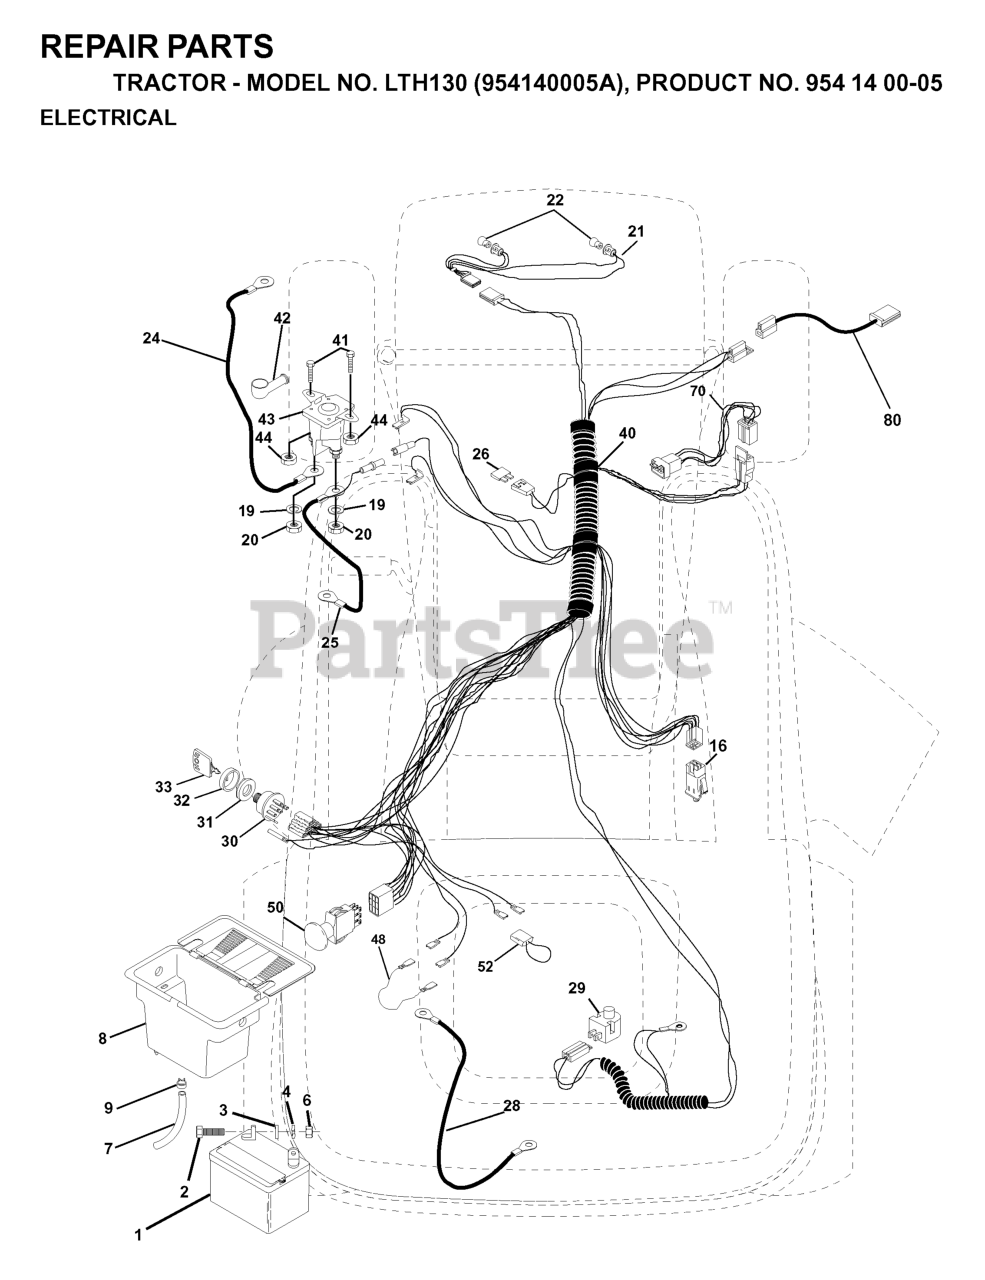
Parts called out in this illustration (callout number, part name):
1	BATTERY
2	BOLT.HEX.1/4.X.3/4.DICHROMATE
4	LOCKWASHER
6	NUT
7	TUBE BATTERY DRAIN
8	CASE BATTERY MECH HINGE
9	HOSE CLAMP T
16	SWITCH INTERLOCK
19	LOCKWASHER
20	NUT
21	HARNESS LIGHT SOCKET
24	BATTERY CABLE GT
25	CABLE BATTERY
28	CABLE T
29	RP.SWITCH.PLUNGER.NC.GRAY
30	SWITCH.IGNITION.4.POSITION
31	NUT IGNITION
32	COVER SWITCH KEY
33	KEY.MOLDED.GENERIC
40	IGN HARNESS
41	BOLT
42	TERMINAL COVER
43	SOLINOID
44	Nut, Keps Blk Hex 1/4-20 UNC
48	ADAPTER.AMMETER
50	SWITCH PTO 3 PDT
52	WIRE PROTECTION LOOP
70	HARNESS ENG. KOHLER
80	HARNESS, CLUTCH
